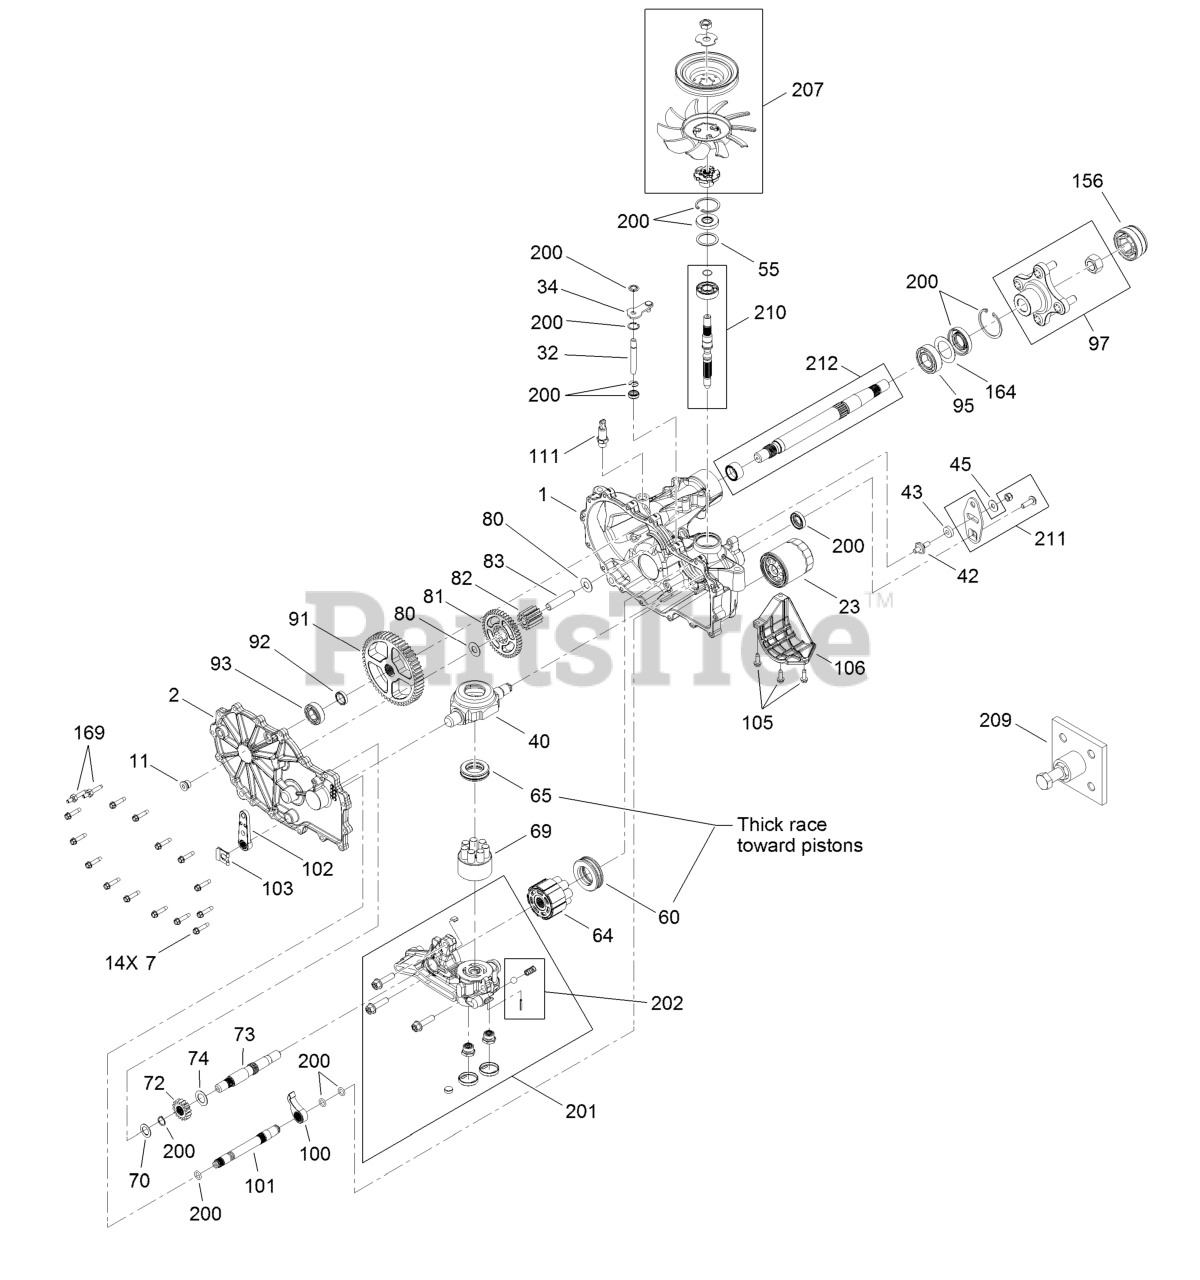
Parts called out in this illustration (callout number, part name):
1	MAIN HOUSING KIT
2	LH SIDE COVER KIT
7	SCREW-HHF
11	PLUG-THREAD, STRAIGHT
23	ELEMENT-OIL FILTER, HYD
32	ROD-BYPASS
34	ARM-BYPASS
40	SWASHPLATE-TRUNNION
43	PUCK-FRICTION
60	BEARING-THRUST
64	MOTOR CYLINDER BLOCK KIT
65	BEARING-THRUST
69	PUMP BLOCK ASM
70	WASHER-FLAT
72	GEAR-16T
73	SHAFT-MOTOR
81	GEAR-43T
82	GEAR-11T
83	PIN-JACKSHAFT
91	GEAR-54T
93	BEARING-BALL
95	BEARING-BALL
97	HUB KIT
100	PAWL-BRAKE
101	SHAFT-BRAKE, INBOARD
102	HANDLE-BRAKE
103	CLIP-RETAINING
106	GUARD-FILTER, LH
111	ADAPTER-STRAIGHT
156	COVER-NUT, AXLE
200	SEAL KIT
201	CENTER SECTION KIT
202	CHARGE RELIEF KIT
207	FAN PULLEY KIT
210	INPUT SHAFT KIT
211	CONTROL ARM KIT
212	AXLE SHAFT KIT
